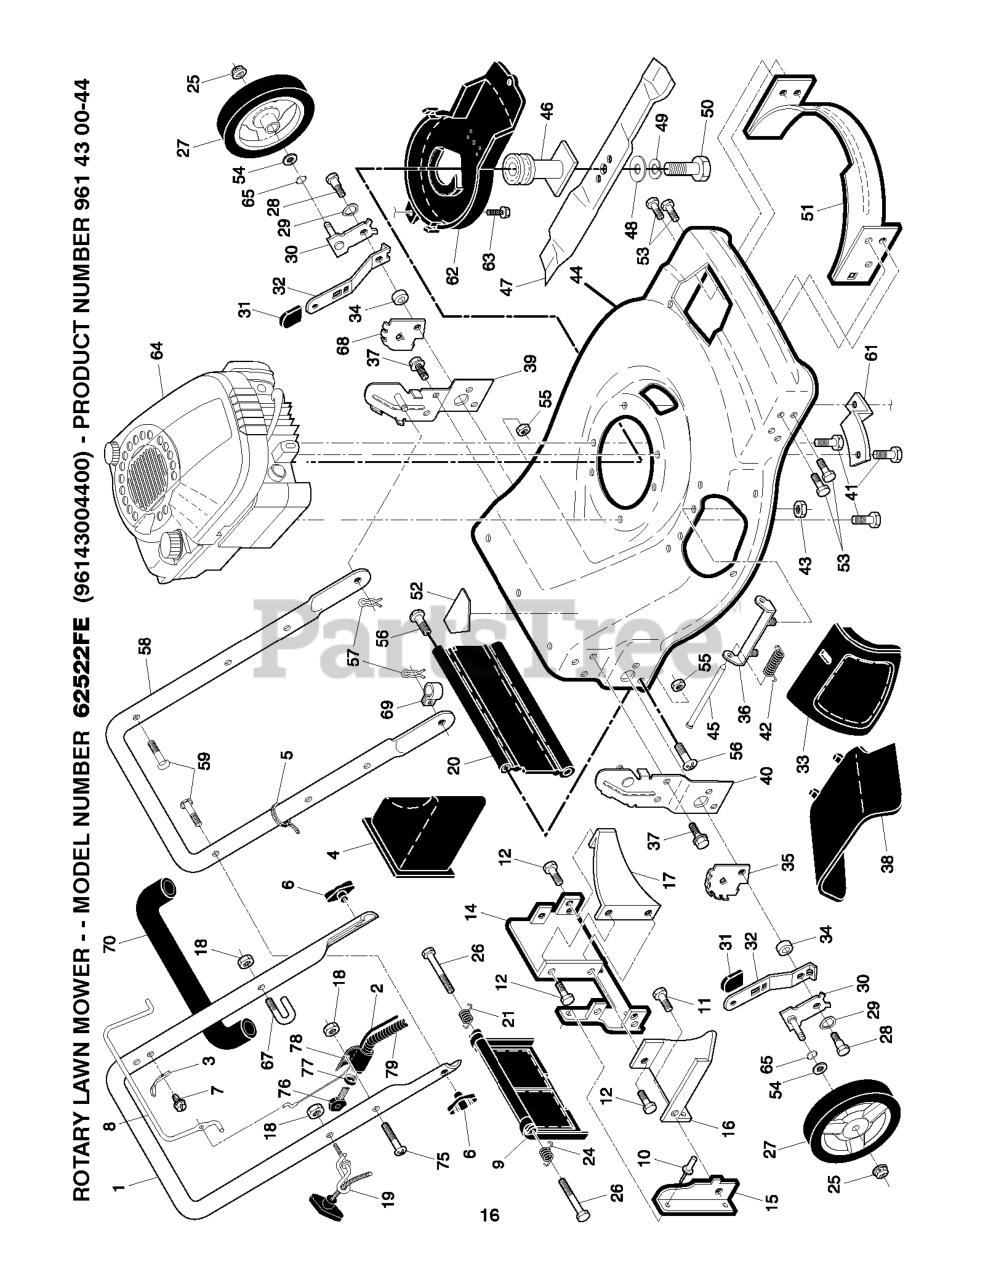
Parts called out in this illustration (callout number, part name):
1	HANDLE.ASM.UP.CREASED.GRAY
2	CABLE.MZR.W/KEY.START SW.51.62
3	BRACKET UPSTOP
4	PLUG.MULCH.22RD
5	TIE GUIDE
6	KNOB, DEFLECTOR
8	BAIL.MZR.CREA.ORANGE
9	REAR DOOR ASSY
10	RIVET BLIND
11	SCREW.HXTAP.10-24
14	PLATE.BACK
15	SIDE BAFFLE
16	DISCHARGE BAFFLE
17	REAR BAFFLE
18	NUT
19	RB GUIDE.ROPE.STD.BLK.ZIN WSL
20	SKIRT.REAR.22RD/SD.FO/VE
21	SPRING.LH.22.REAR.DOOR.EZ.EMPT
24	SPRING.RH.22.REAR.DOOR.EZ.
25	NUT.HEX.FLANGE.3/8-16.LO(3 2)
27	WHEEL & TIRES ASSY, FRONT
28	BOLT
29	WASHER.CURVED.CYLINDRICAL
30	AXLE ARM ASSY.
31	SELECTOR KNOB
32	SELECTOR SPRING, FRONT
33	DOOR.MULCH.22.REAR.FWGD.GREY
34	SPACER.HEIGHT.ADJUSTER
35	WHEEL ADJUSTING BRACKET
36	BRACKET.ASM.HINGE.21.FWGD.
37	SCREW
38	DEFLECTOR.CLIPPING.22.GREY
39	BRACKET.ASM.HDL.LT.EZEM.22.ORA
40	BRACKET.ASM.HDL.RT.EZEM.22.ORN
41	BOLT 3/8-16X1-1/8
42	SPRING.TORSION
43	LOCKNUT.NYLOC.1/4-20
44	HOUSING.22.TORUS.FWD.ORANGE.WA
45	ROD.HINGE.21
46	BLADE ADAPTOR / PULLEY
47	BLADE.22.MULCH.STANDARD
48	WASHER,HARDEN
49	LOCKWASHER
50	SCREW, HEX HD 3/8-24 X 1-3/8
51	FRONT BAFFLE KIT
52	DANGER DECAL
53	SCREW 1/4X20
54	WASHER.FLAT.1/2
55	LOCKNUT
56	HINGE SCREW
57	HAIRPIN COTTER
58	HANDLE.LOWER.PNT
59	BOLT, HANDLE 5/16-18X1.75
61	BRACKET
62	DEBRIS SHIELD
63	SCREW.HEX.WSH
65	O-RING..070X.487.NEOPRENE
67	CLIP.WIREFORM.PACK.TOR
68	WHEEL ADJUSTING BRACKET LH
69	CLIP.CABLE.BLK
70	GRIP, FOAM
75	SCREW.(COMBINATION CONTROL)
76	KEY.MOLDED
77	NUT.CAP.SNAP-ON.KEY START
78	HARNESS.WIRING.CONTROL
79	HARNESS.WIRING.CONTROL
